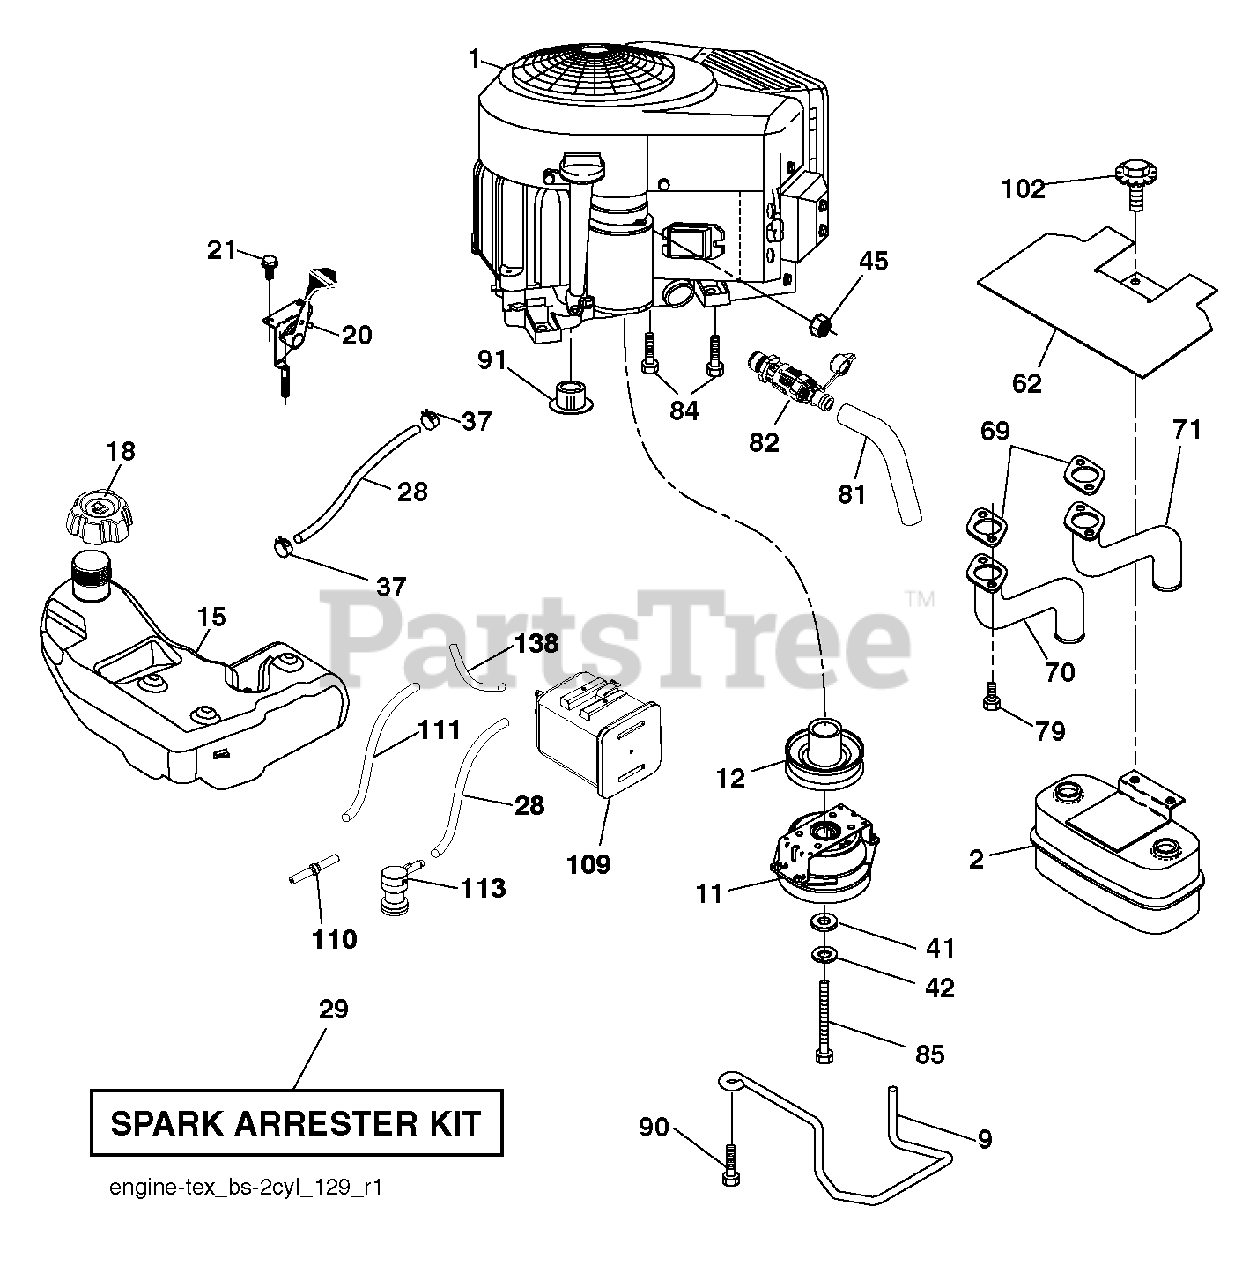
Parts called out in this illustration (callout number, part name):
2	MUFFLER.ASM.TWN.EXTNDED.DFLCTR
9	KEEPER.BELT.ENGINE
11	CLUTCH.OGURA.5.0PD.GT1.5A-EH07
12	PULLEY.ENGINE.ENX
15	TANK.ASM.FUEL.3GA.CARB
18	CAP ASSY FUEL 3" GRAY
20	THROTTLE.COBRA.38"READSTART.BK
21	SCREW.#10 X 0.750.BOS
28	LINE.FUEL.64"REAR.EMIS
29	KIT.SPARK ARRESTOR 794945 B&S
37	HOSE CLAMP
42	LOCKWASHER
45	NUT
62	SHIELD.HEAT.MUFFLER
69	GASKET.MUFFLER
70	EXHAUST.TUBE.LH.BS/TWIN
71	EXHAUST.TUBE.RH.B&S.TWIN.INTEK
79	SCREW.SOCKET.HEAD.5/16-18
81	TUBE, DRAIN OIL ASM.
82	VALUE.OIL.DRAIN
84	SCREW.3/8-16
85	BOLT HEX 7/16-20 X 3.75 GR. 5
90	SCREW 3/8-16X1
91	PARTNER DECAL,
102	SCREW
109	CANNISTER, CARBON
110	VALVE.ASM.ANTI-SLOSH
111	RP PURGE LINE
113	VALVE.SLANT.CARTRDG.90 DEG.TEX
138	PURGE.LINE.36"REAR.CALIFORNIA
